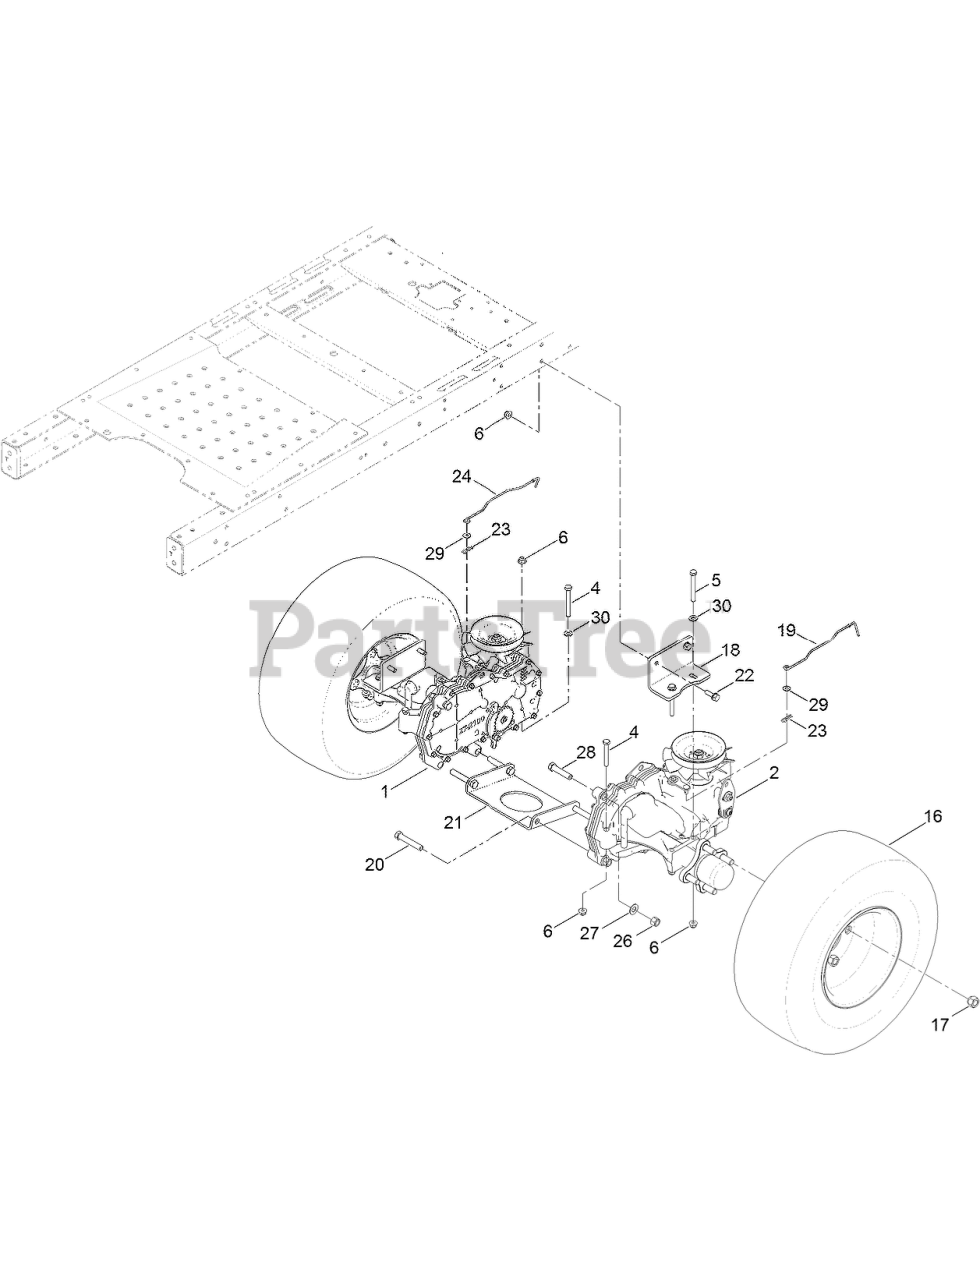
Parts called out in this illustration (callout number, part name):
1	RH HYDRO TRANSAXLE ASM
2	LH HYDRO TRANSAXLE ASM
4	SCREW-HH
5	SCREW-HH
6	NUT-HF, NI
16	2 PLY WHEEL AND TIRE ASM
17	NUT-LUG
18	MOUNT-HYDRO
19	ROD-BYPASS, LH
20	SCREW-HH
21	PLATE-CROSS, HYDRO
22	SCREW-HHF
23	PIN-COTTER
24	ROD-BYPASS, RH
26	NUT-LOCK, NI
27	WASHER-FLAT
28	SCREW-HH
29	WASHER
30	WASHER-PLAIN
